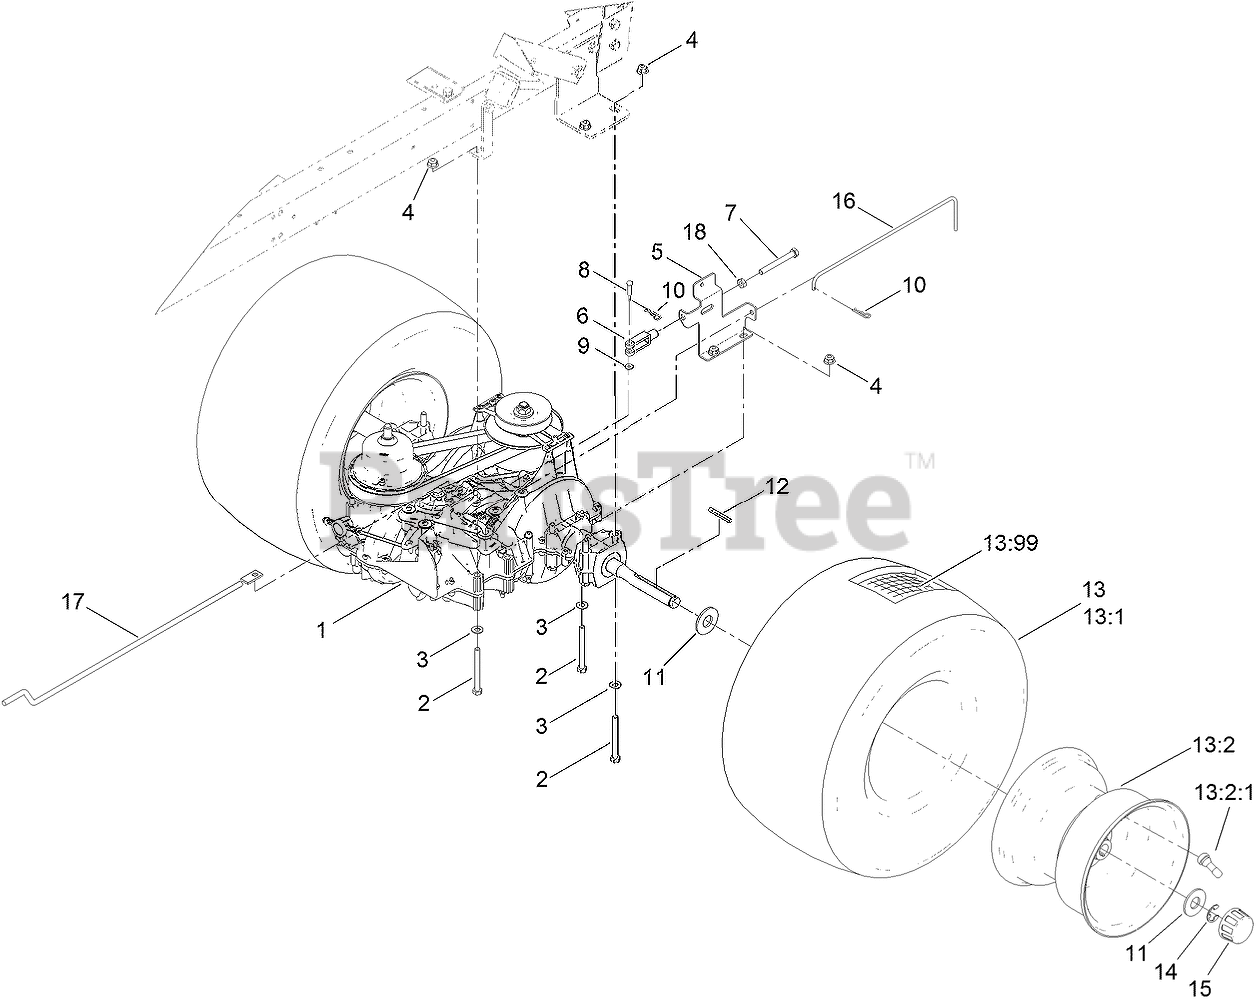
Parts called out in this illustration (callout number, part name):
1	TRANSMISSION, CVT-AUTO
2	SCREW-HH
3	WASHER-PLAIN
4	NUT-HF, NI
5	BRACKET-NEUTRAL
6	YOKE-ADJUSTABLE
7	SCREW-HH
9	WASHER-FLAT
10	PIN-COTTER
11	WASHER-PLAIN
12	KEY-SQUARE
13	REAR WHEEL AND TIRE ASM
13:1	TIRE
13:2:1	STEM-VALVE
13:99	Tube
14	E-RING
15	CAP-HUB
16	ROD-BYPASS
17	ROD-CONTROL, MOTION
18	NUT-JAM
